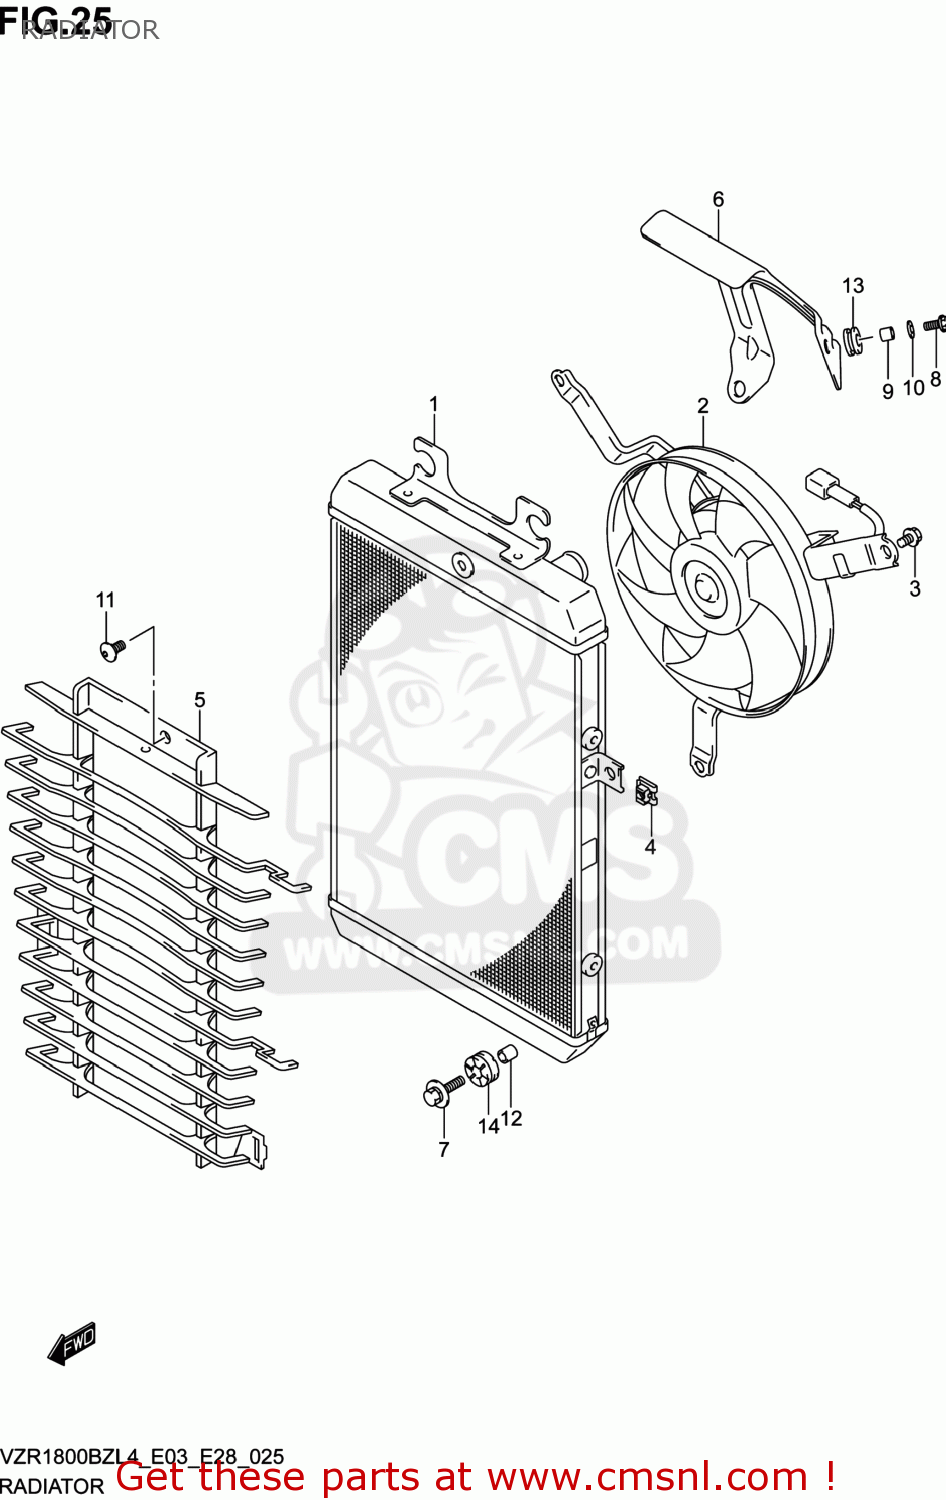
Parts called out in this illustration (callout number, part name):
1	RADIATOR ASSY,WATER
2	FAN ASSY,RADIATOR
3	BOLT,FAN ASSY
4	NUT,FAN ASSY
5	GUARD,RADIATOR
6	SHIELD,RADIATOR HEAT
7	BOLT(6X25)
8	BOLT
9	SPACER(6.2X8.3X5.7)
10	WASHER(6.5X20X1.2)
11	SCREW(6X12)
12	SPACER(6.5X10X12)
13	CUSHION
14	CUSHION
